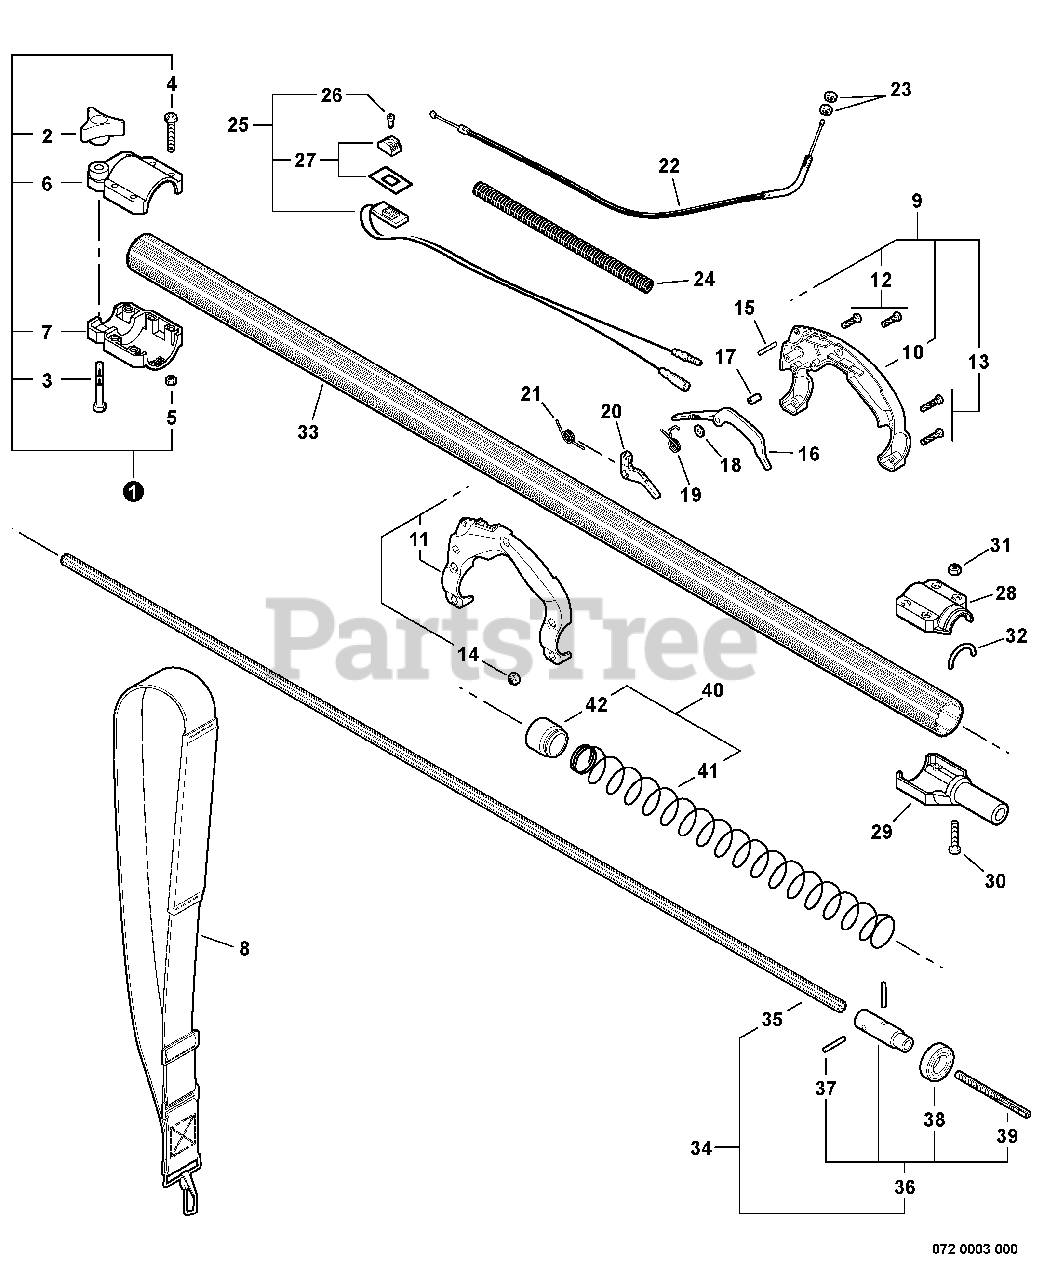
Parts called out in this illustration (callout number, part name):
1	CLAMP ASSY
2	THUMBSCREW
4	SCREW, TORX 10-24 UNC 1-1/4
5	NUT, LOCK 10-24 UNC
6	COLLAR, UPPER
7	COLLAR, LOWER
8	STRAP ASSY, SHOULDER
9	HANDLE SET, REAR
10	HANDLE, LEFT REAR
11	HANDLE, RIGHT REAR
12	SCREW, TORX 10-24 UNC 1-1/4
13	SCREW, TORX 10-24×1.5
14	NUT, LOCK 10-24 UNC
15	PIN, LOCATING 0.17 OD×0.75 L
16	LOCKOUT, THROTTLE
17	COLLAR 5.08×14.5
18	WASHER 5.5×12×0.8
19	SPRING, TORSION Ø0.39 I.D.
20	TRIGGER, THROTTLE
21	SPRING, TORSION
22	CABLE, THROTTLE
24	TUBE, FLEXIBLE
25	SWITCH, ON-OFF
26	SCREW 3×10
27	KNOB, SWITCH - ORANGE
28	CAP, MAIN PIPE
29	ADAPTER, LOWER DRIVE SHAFT
30	SCREW, TORX 10-24×1.5
31	NUT, LOCK 10-24 UNC
33	PIPE, MAIN
34	SHAFT ASSY, DRIVE
35	DRIVESHAFT
36	CONNECTOR, DRIVE SHAFT
38	BEARING, BALL 6002 DDU
40	BUSHING ASSY, FLOATING
41	SPRING, COMPRESSION
42	BUSHING, FLOATING
